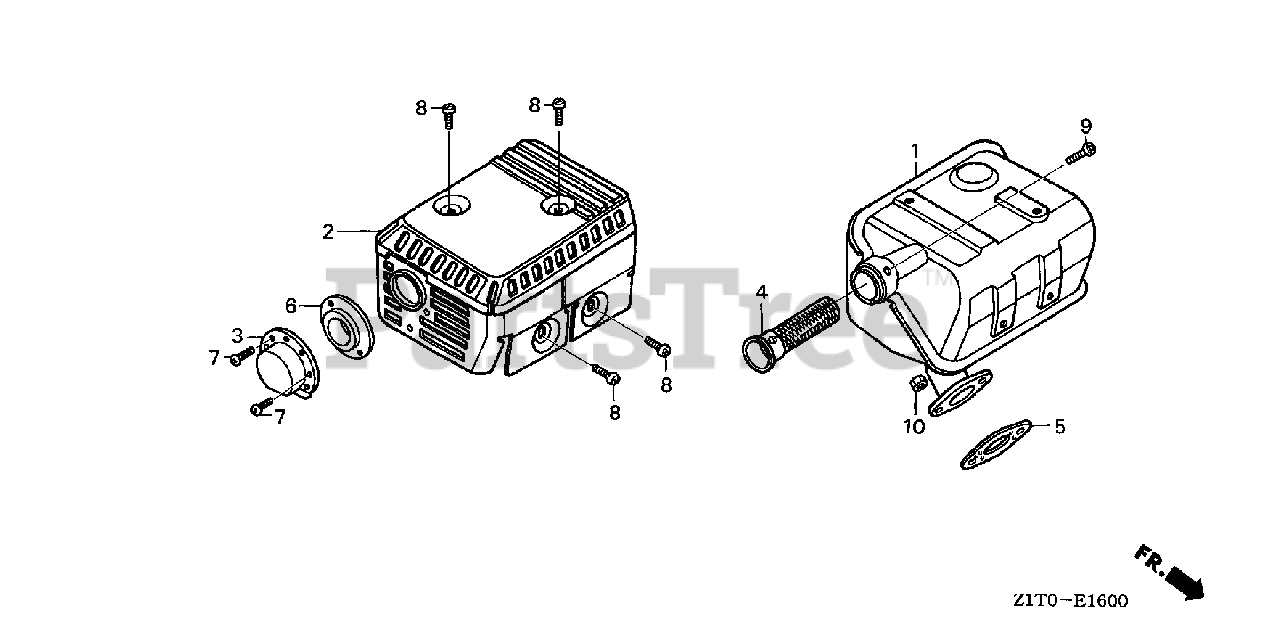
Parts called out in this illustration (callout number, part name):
1	MUFFLER (ARRESTER)
1	MUFFLER
2	PROTECTOR, MUFFLER (STD)
4	ARRESTER, SPARK
5	GASKET, MUFFLER
8	SCREW, TAPPING (5X8)
9	SCREW, TAPPING (4X6)
10	NUT, HEX. (8MM)
